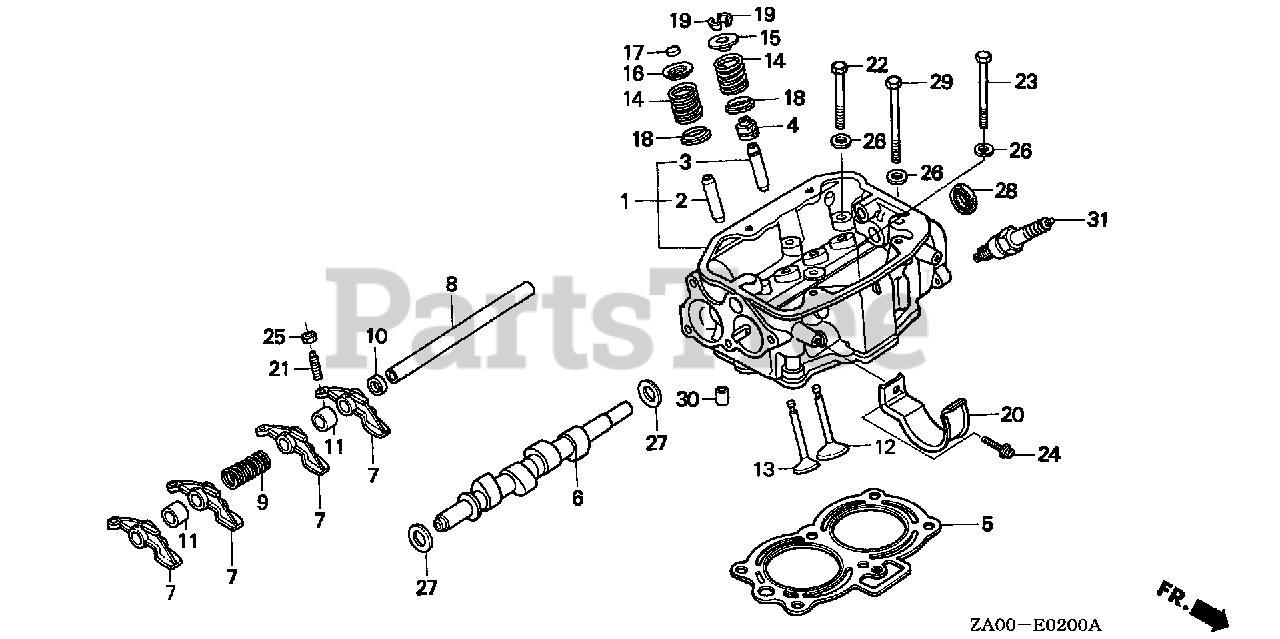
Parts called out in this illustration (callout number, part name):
1	CYLINDER HEAD
2	GUIDE, EX. VALVE
3	GUIDE, VALVE (OS)
4	SEAL, VALVE STEM
5	GASKET, CYLINDER HEAD
6	CAMSHAFT
7	ARM, VALVE ROCKER
8	SHAFT, VALVE ROCKER ARM
9	SPRING, VALVE ROCKER ARM
10	COLLAR A, VALVE ROCKER ARM
11	COLLAR B, VALVE ROCKER ARM
12	VALVE, IN.
13	VALVE, EX.
14	SPRING, VALVE
15	RETAINER, VALVE SPRING
16	RETAINER, VALVE SPRING
17	ROTATOR, VALVE
18	SEAT, VALVE SPRING
19	COTTER, VALVE
20	CLAMP, WATER HOSE
21	SCREW, TAPPET ADJ.
22	BOLT, HEAD (8X70)
23	BOLT, HEX. (8X55)
24	BOLT, FLANGE (6X25) Use up to Engine SN 2056819.
25	NUT, TAPPET ADJ.
26	WASHER, HEAD (8MM)
27	WASHER, THRUST (16MM)
28	OIL SEAL (16X28X6)
29	BOLT, HEX. (8X100)
30	PIN A, DOWEL (10X16)
31	SPARK PLUG (BPR4HS) (NGK)
31	SPARK PLUG (BPR5HS) (NGK)
